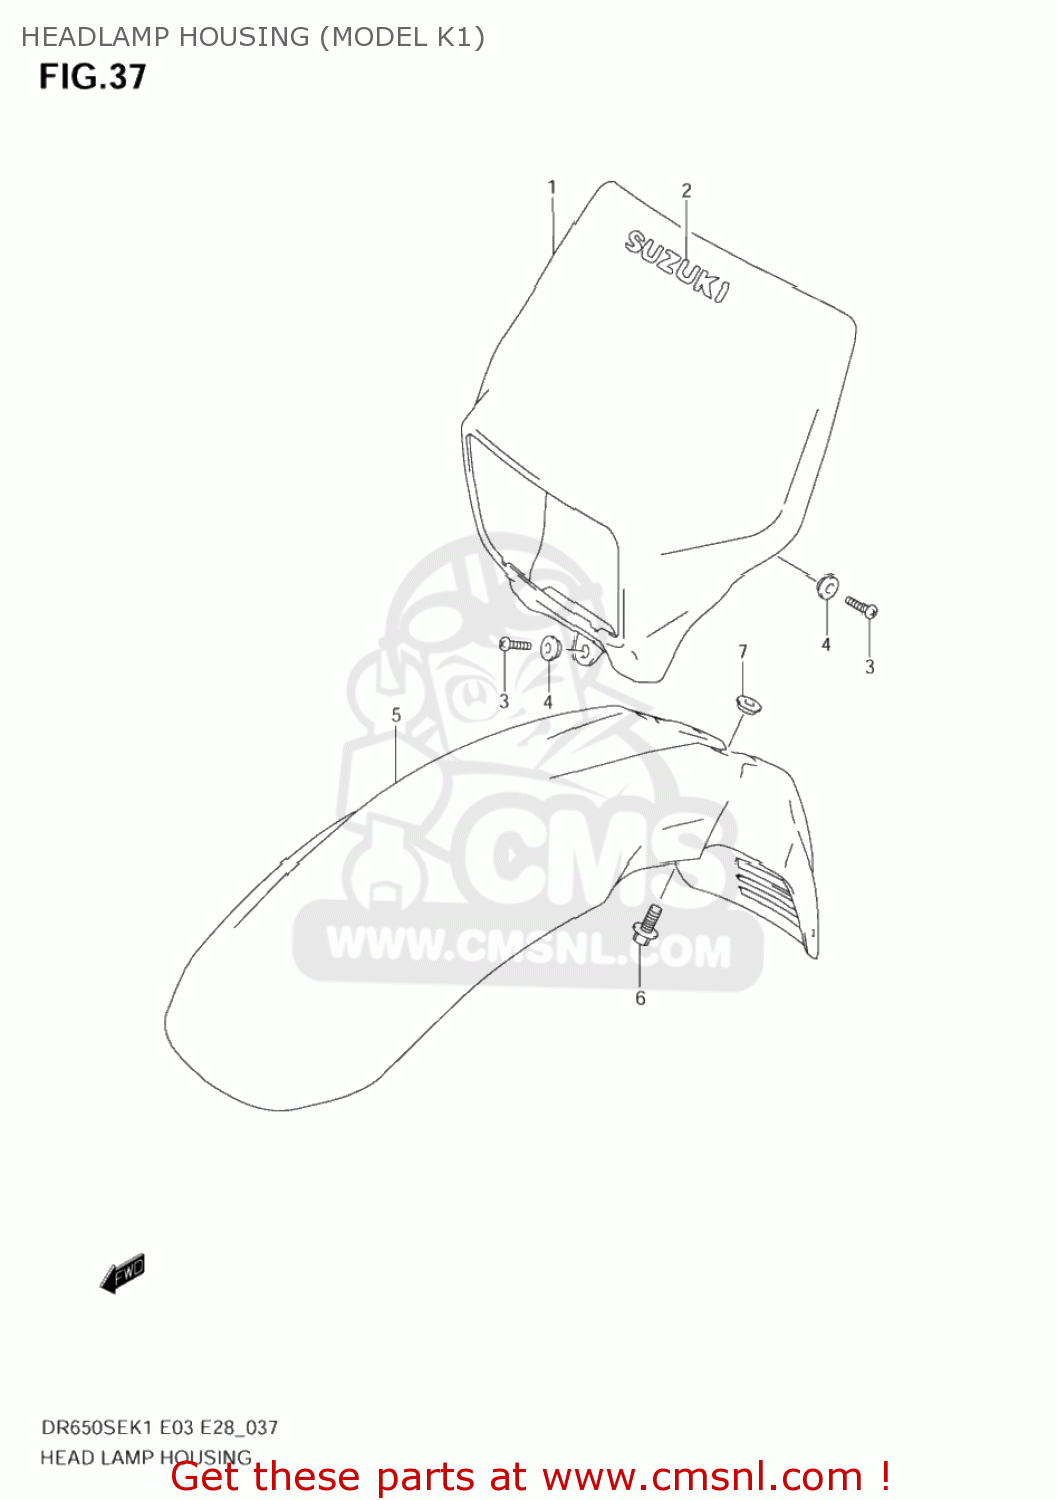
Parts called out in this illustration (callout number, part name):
1	COVER,HEADLAMP
2	EMBLEM,SUZUKI
3	SCREW 6X12
4	WASHER
5	FENDER,FR
6	BOLT(6X16)
7	WASHER
